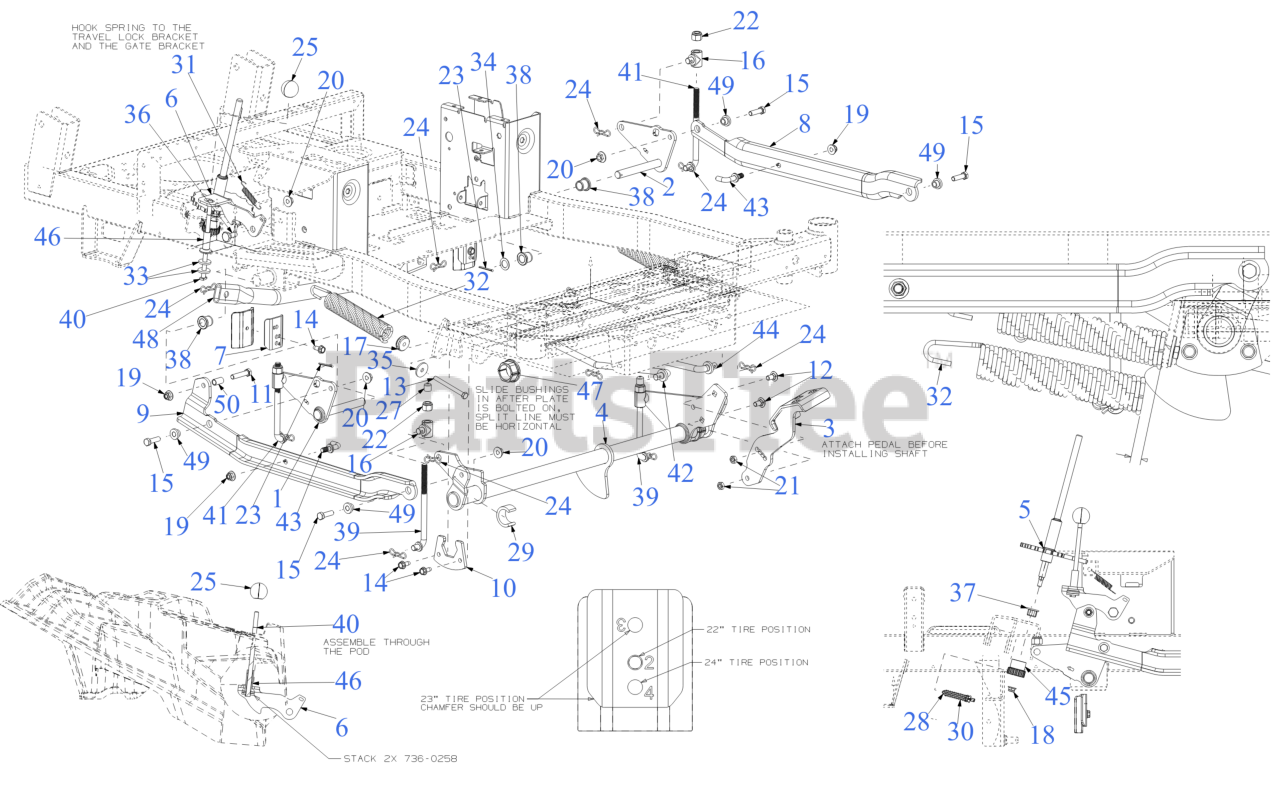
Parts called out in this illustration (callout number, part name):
1	BELLCRANK BRACKET (RH)
2	BELLCRANK BRACKET (LH)
3	DECK LIFT PEDAL
4	LIFT TUBE (FRONT)
5	DECK HEIGHT ADJUSTMENT ROD
6	TRAVEL LOCK PLATE
7	UPSTOP BRACKET
8	LIFT LINK (LH)
9	LIFT LINK (RH)
10	LIFT TUBE BRACKET
11	HEX SCREW 3/8-16 x 1.75 GR5
12	CARRIAGE BOLT 3/8-16 x .750 GR5
13	SCREW 5/16-18 x 3.50 GR5
14	SCREW 5/16-18 x .750
15	SCREW 3/8-16 x 1.25 GR5
16	LIFT ROD FERRULE
17	LIFT SPRING INSERT
18	FLANGE LOCK NUT 5/16-18
20	FLANGE LOCK NUT
21	HEX JAM NUT 3/8-16 GR5
22	HEX LOCK NUT NYLON
23	COTTER PIN
24	BOW TIE COTTER PIN
27	LIFT ROD END CAP
28	DETENT PLUNGER
29	LIFT TUBE SPACER
30	COMPRESSION SPRING .531 OD 1.75 LG
31	EXTENSION SPRING 2.675"
32	EXTENSION SPRING
33	FLAT WASHER .385 x 1.00 x .135
34	FLAT WASHER
35	WASHER-5/16 x 1.25X 1.27
36	SHOULDER SCREW
37	HEX FLANGE BEARING .506ID x .590LG
38	FLANGE BUSHING
39	DECK LIFT ROD 6.875"
40	TRAVEL LOCK ROD
41	DECK LIFT ROD 6.562"
42	DECK CONTROL ROD (RH)
43	LIFT SPRING MOUNTING ROD
44	DECK CONTROL ROD (LH)
45	DECK HEIGHT DETENT HUB
46	LOCK ROD SLEEVE SPACER
47	HEX FLANGE BEARING
48	DECK STABILIZER TUBE
49	SHOULDER SPACER 0.39x0.575x0.312
50	SPACER .380x.500x.875
